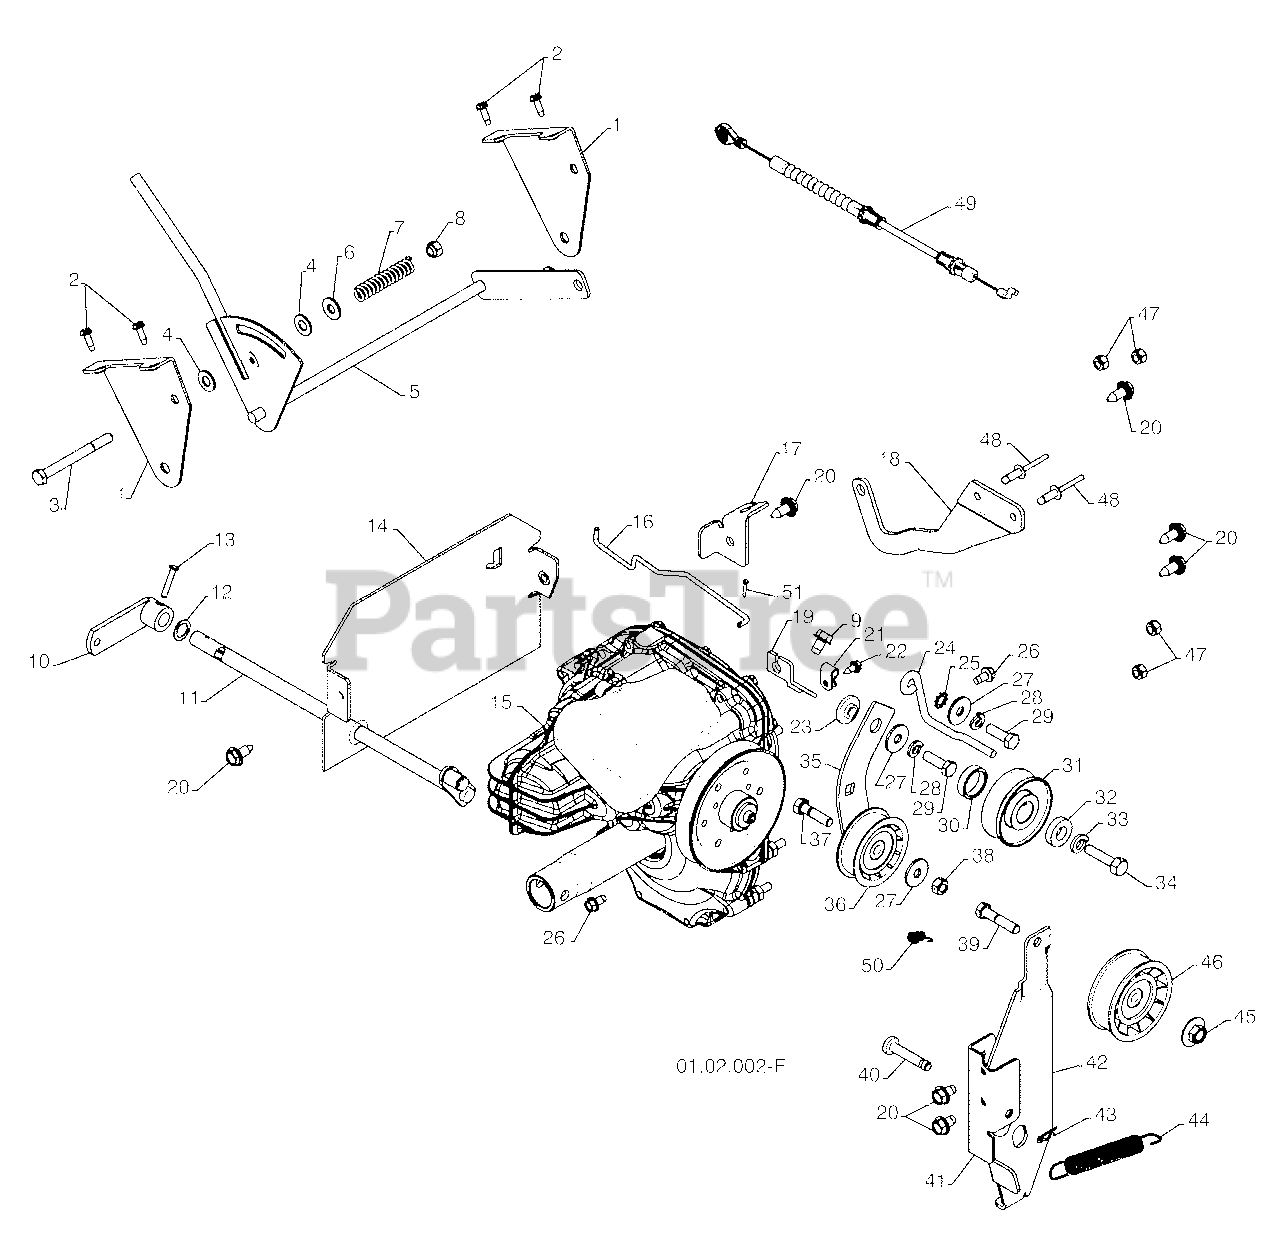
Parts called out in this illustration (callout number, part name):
1	SHIFT BRACKET
2	SCREW 10-24 X .625
3	SCREW 5/16-18 X 3.25
4	PLASTIC WASHER
5	SHIFT ASSEMBLY
7	FRICTION SPRING
8	NUT 5/16-18
9	BOLT 5/16-18 X .500
10	CONTROL ARM
11	CONTROL SHAFT
13	CLEVIS PIN
14	REAR PLATE
15	TRANSMISSION
17	REAR CABLE BRACKET
18	CONTROL ARM
19	FRONT CABLE BRACKET
20	SCREW 5/16-18 X .750
22	SCREW .12 X .50
23	BUSHING
24	BELT GUIDE
25	LOCKWASHER 5/16
26	SCREW 1/4-20 X .500
28	LOCKWASHER 5/16
29	SCREW 5/16-18 X 1.00
31	ENGINE TRACTION PULLEY
33	LOCKWASHER 3/8
34	SCREW 3/8-24 X 1.38
35	TRACTION IDLER ARM
36	IDLER PULLEY
37	SCREW 5/16-18 X 1.25
38	NUT 5/16-18
39	SCREW 5/16-18 X 1.50
41	IDLER PIVOT BRACKET
42	IDLER BRAKE ARM
44	BRAKE SPRING
45	NUT 5/16-18
47	NUT 1/4-20
48	POP RIVET 1/4 X .475
49	CLUTCH CABLE
50	TRACTION SPRING
51	RETAINER CLIP
